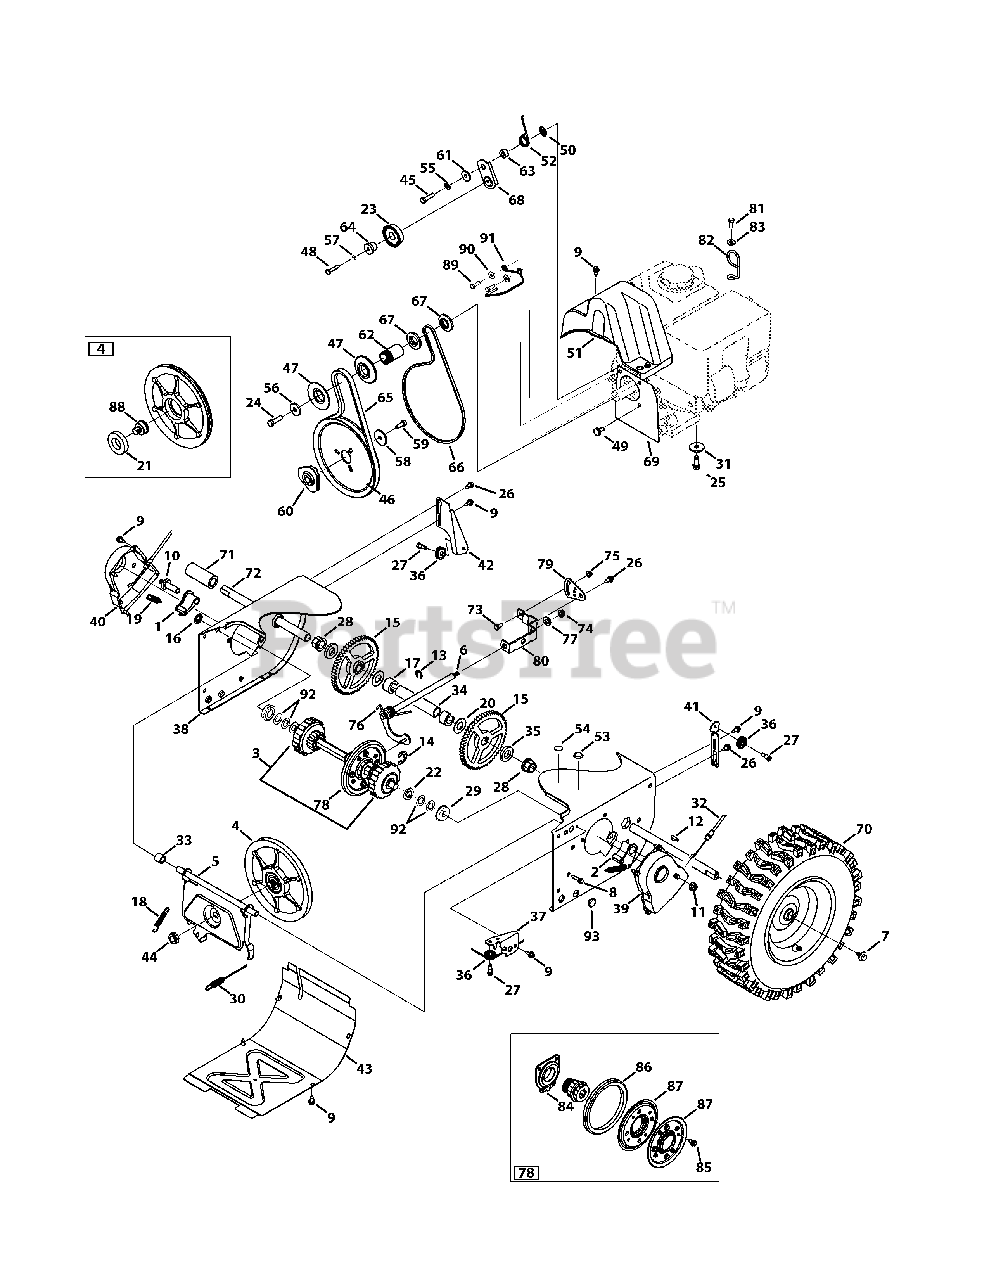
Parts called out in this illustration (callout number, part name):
1	Dogg Assembly, RH
2	Dogg Assembly, LH
3	Drive Shaft Assembly
4	Friction Wheel Disc Assembly
5	Friction Wheel Support Bracket
6	Rod Shift Assembly
7	Screw, 5/16-24 x .750
8	Screw, 1/4-20 x 1.000
9	Screw, 1/4-20 x .625
10	Actuator Shaft
11	Nut, Flangelock, 3/8-16
12	Hi-Pro Key, 3/16 x 3/4 DIA
14	Retainer Ring
16	Nut, Speed, .500
17	Spacer, .76 x .75
18	Extension Spring, .380 x 2.500
19	Extension Spring, .500 x 1.71
20	Washer, Flat, .76 x 1.49
21	Ball Bearing, 30 x 55 x 13
22	Spacer, .68 ID x 1.25 OD x .20
23	Idler Pulley Assembly
24	Hex Head Screw, 3/8-24 x 1.25
25	Taptite Sems Screw, 3/8-16 x 1.000
26	Screw, Shoulder, .368 x .113 x 1/4-20
27	Screw, Shoulder, .340 x .335 x 1/4-28
28	Hex Flange Bearing, .75 ID
29	Ball Bearing, 17 x 40 x 12
30	Drive Clutch Cable
31	Washer, Flat, .38 x 1.38
32	Steering Cable
33	Spacer, .508 x .75
34	Axle Support Tube
35	Spacer, Axle
36	Cable Roller
37	Auger Cable Guide Bracket
38	Wheel Drive Frame (24", 26" & 28")
39	Shaft Retainer, LH
40	Shaft Retainer, RH
41	Auger Clutch Cable Guide Bracket
42	Drive Clutch Cable Guide Bracket
44	Nut, Flange, 5/8-18
45	Hex Head Screw, 5/16-24 x 1.25
46	Auger Pulley, 8.1 x .5
47	Pulley, Half, 2.600
48	Taptite Screw, 1/4-20 x 1.250
49	Shoulder Screw, .500 x .145
50	Nut, Push-On, .25 Dia.
51	Belt Cover
52	Spring, Torsion, .850 x .333
53	Plug, 3/8 ID
54	Plug, 1/2 ID
55	Washer, Lock, 5/16
56	Washer, Flat, .45 x 1.5
57	Washer, Lock, 1/4
58	Washer, Flat, .34 x 1.50
59	Hex Head Screw, 5/16-24 x .875
60	Pulley Adapter, .75 DIA
61	Spacer, Shoulder, .3175 x .500
62	Spacer, .875 x 1.185
63	Spacer, .340 x .750
64	Spacer, Shoulder, .260 x .785
65	Belt, .500 x 37
66	Belt, 3/8 x 35.68
67	Pulley, Half, 3/8 x 1.7160
68	Drive Idler Bracket
69	Cover Plate
70	Wheel, LH (24" & 26")
70	Wheel, RH (24" & 26")
71	Spacer, 1.25 x .75 x 3.00
72	Axle, .75 x 11.12
73	Hex Head Screw, 1/4-20 x .620
74	Nut, Flange Lock, 5/16-18
75	Nut, Flange Lock, 1/4-20
76	Spring, Torsion, .750 x .968
77	Washer, Flat, .469 x .875 x .105
78	Friction Wheel Assembly
79	Speed Selector Pivot Bracket
80	Speed Selector Shift Bracket
81	Hex Head Screw, 1.25 x 20
82	Cable Guide
83	Washer, Flat, .330 x .630
84	Bearing Assembly, Friction Wheel
85	Screw, 5/16-18 x .75
86	Friction Wheel, 5.5 OD
87	Friction Wheel Plate
88	Friction Pin, Disc Bearing
89	Hex Head Screw, 5/16-24 x 1.00
90	Washer, Flat, .349 x .879
92	Flat Washer, .67 x 1.174 x .02
93	Plug, 5/8 Hole
